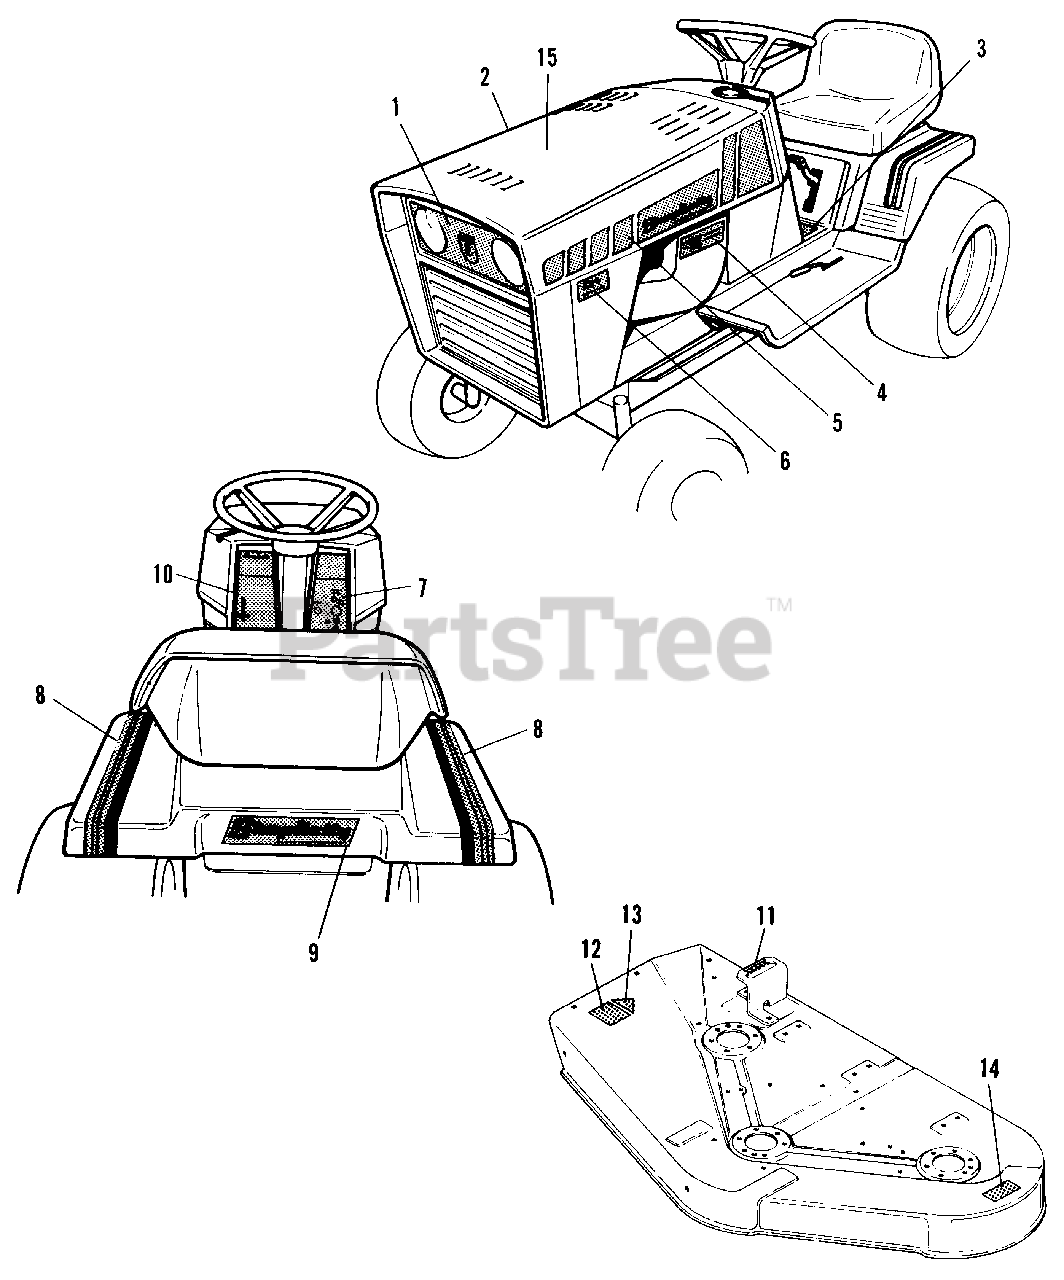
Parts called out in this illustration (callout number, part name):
1	DECAL, Grille
2	DECAL, Hood, R.H.
3	DECAL, Shift
4	DECAL, Engine
5	DECAL, Hood, L.H.
6	DECAL, 5216 Hydro
7	DECAL, Dash, R.H.
8	DECAL, Seat Deck
10	DECAL, Dash, L.H.
11	DECAL, Mower Height
12	DECAL, Warning
13	DECAL, OPEI
14	DECAL, Danger
15	DECAL, Drive Belts (Inside Hood)
